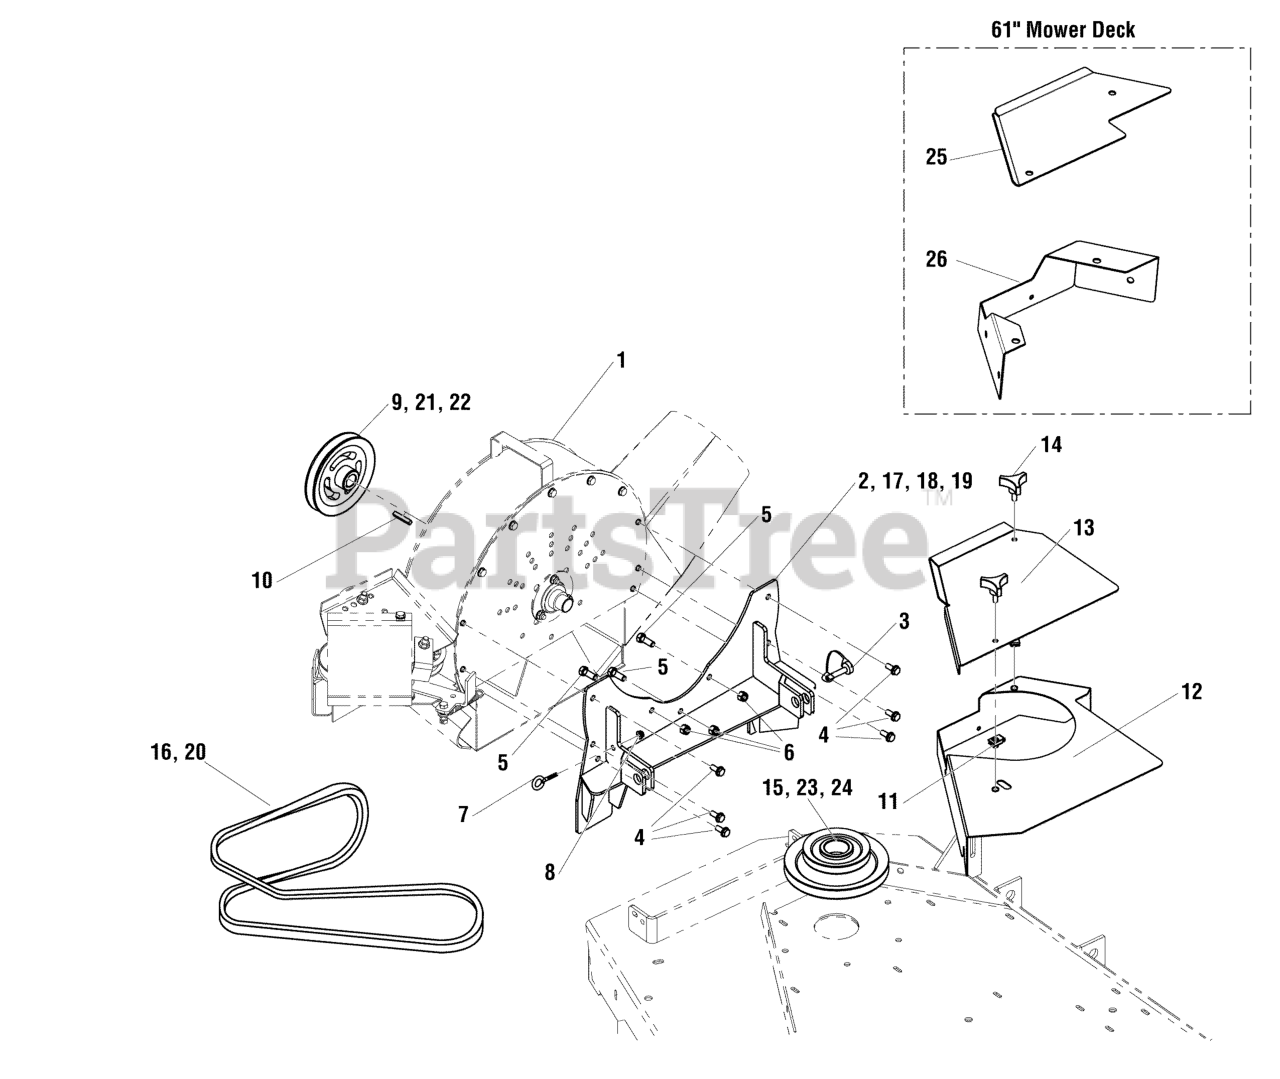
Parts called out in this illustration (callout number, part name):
1	BLOWER ASSEMBLY
2	WELD, BLOWER MOUNT, 61" - BLK
3	SNAPPERPIN, 5/16 X 2
4	BOLT, 5/16-18 X 3/4" SELF LOCK
5	BOLT, 3/8-16 X 1" GD5 CZ
6	NUT, 3/8-16 HEX NYLON LOCK
7	EYE BOLT, 1/4-20 X 2.5, 1THRD, .5EYE,CZ
8	NUT, 1/4-20 HEX NYLOCK FLANGE
9	PULLEY, BLOWER AXLE, 52
10	KEY 1/4 SQ X 1 1/2 LONG
11	BODY CLIP, 5/16-18-7GA MATERIAL
12	GUARD, DECK - BLACK
13	SHIELD, BELT
14	KNOB, PLASTIC, 5/16-18 X 3/4"
15	PULLEY, BLOWER 52" DECK
16	BELT, #7-6717, 88.8" E.L.
17	WELD, BLOWER MOUNT 52 BLACK
18	WELD, BLOWER MOUNT 48 BLACK
19	WELD, BLOWER MOUNT, 52" - BLK
20	BELT, A-SEC, 92.00EL, ARAMID, WRPD
21	PULLEY, BLOWER AXLE, 48
22	PULLEY, BLOWER AXLE, 61
23	PULLEY, BLOWER 48" DECK
24	PULLEY, BLOWER 61" DECK
25	SHIELD, BELT
26	GUARD, DECK - BLACK
